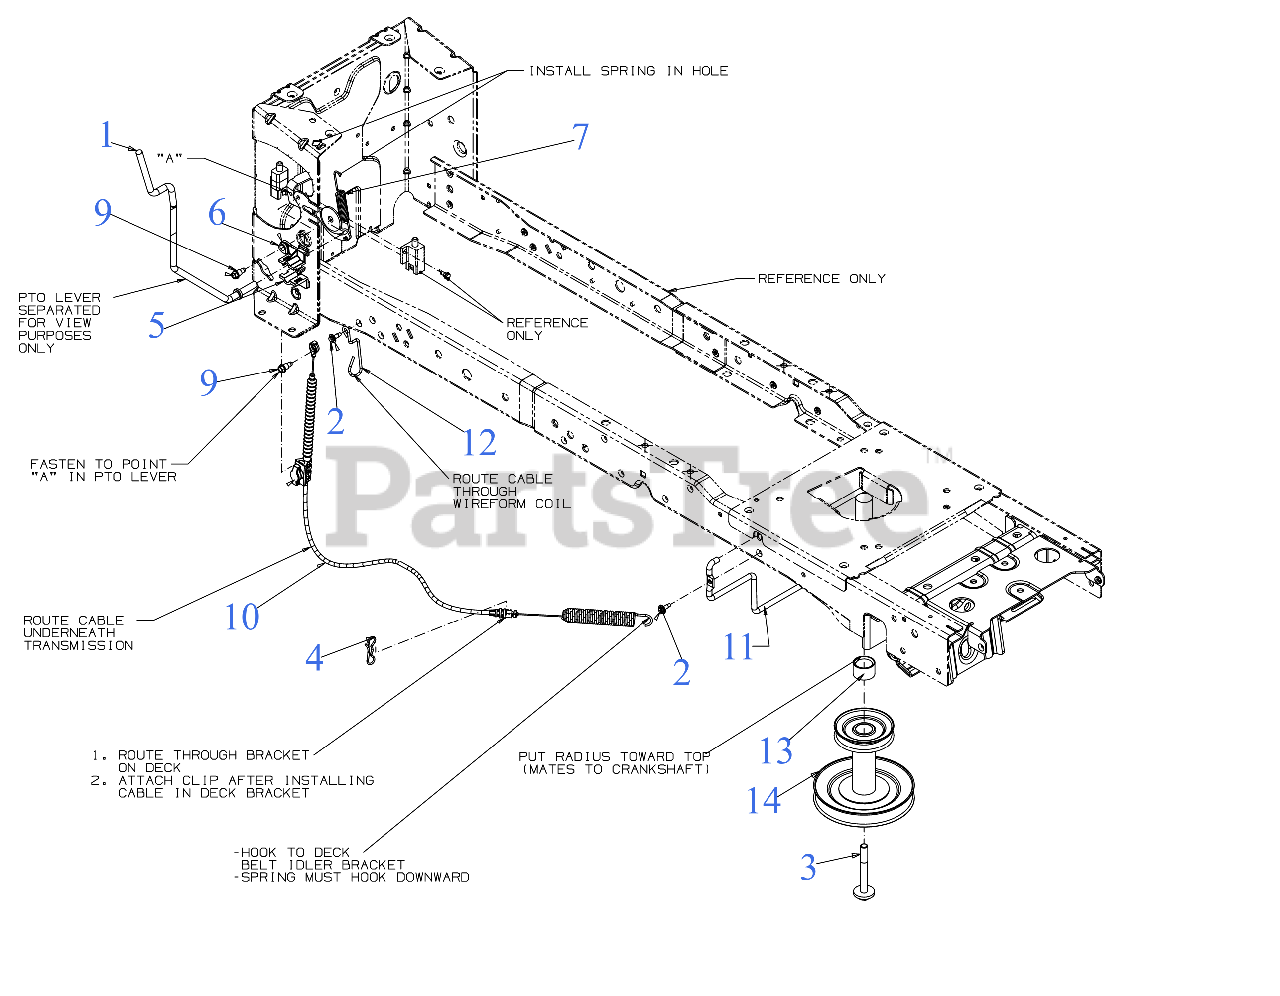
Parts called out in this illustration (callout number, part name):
1	PTO HANDLE ASSEMBLY
2	SCREW M6-1 x .625
3	SCREW 7/16-20 x 3.50
4	BOW TIE COTTER PIN
5	PTO HANDLE BOTTOM BEARING
6	PTO HANDLE TOP BEARING
7	EXTENSION SPRING .56 OD x 4.52
9	SHOULDER SCREW
10	PTO HANDLE CABLE
11	BELT KEEPER ROD
12	CABLE GUIDE WIRE
13	ENGINE PULLEY SPACER
14	ENGINE PULLEY 3.56 x 6.12 DIA
